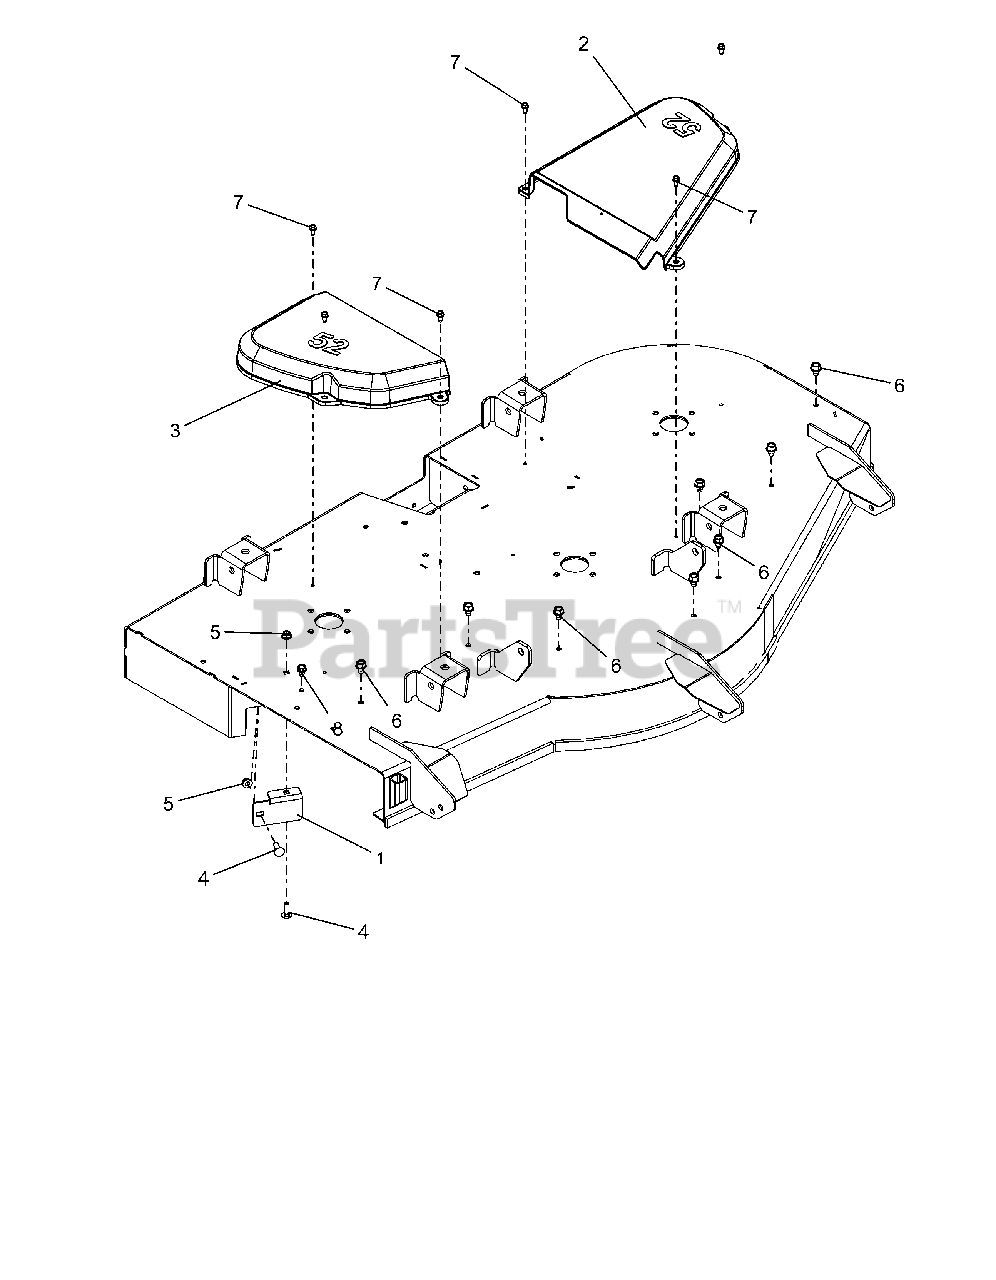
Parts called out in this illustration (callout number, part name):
1	STRIP, DEFLECTOR - 52"
2	COVER, BELT 52" LH
3	COVER, BELT 52" RIGHT
4	BLT,RHSN .31-18X1.00 G5 ZCC
5	NUT,NYL-FLG .31-18 GF ZCC
6	SCR,TAP .375-16X.50 HWH TR ZCC
7	SCR-TAP .25-20X.50 HWH ZCC
8	@SCR-TAP .31-18X.50 HWH TR YWZ
